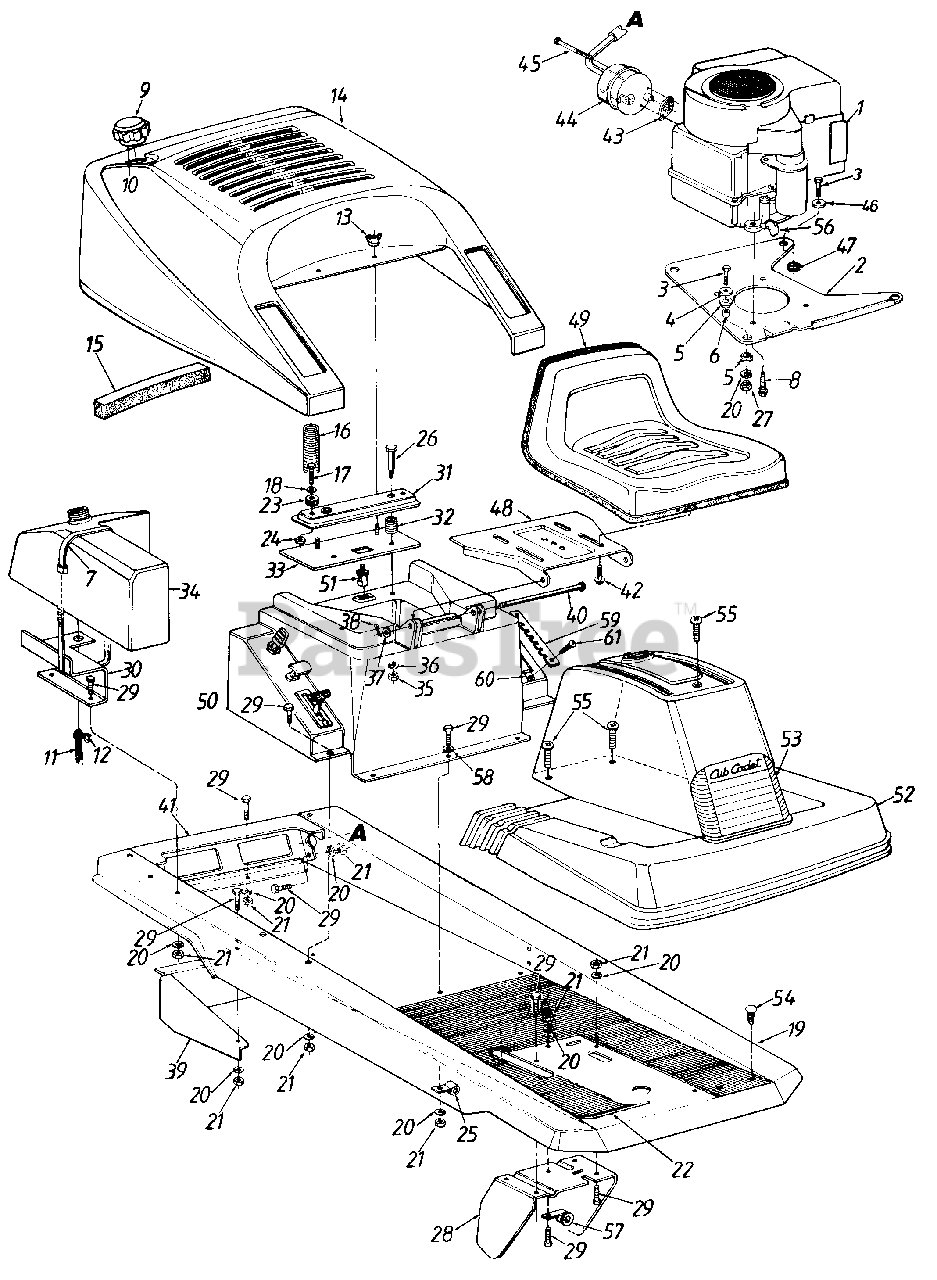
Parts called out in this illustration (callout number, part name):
1	Engine
4	Fl-Wash. .33" I.D. x 1.125" O.D
5	Engine Mounting Grommet
6	Spacer .315" I.D. x .5" O.D.
7	Cable Tie 30.6" Lg.
8	Hex Wash. Hd. Self-Tap Scr. 3/8-16 x 1.25" Lg.
10	Gas Cap Gasket
11	Gas Line
12	Hose Clamp
13	Wing Nut 1/4-20 Thd.
14	Rear Engine Cover
15	Foam Strip-2 Req'd.
16	Compression Spring 2.35" Lg.
17	Hex Bolt 5/16-18 x 718" Lg. (Gr. 5)
18	Fl-Wash. .344" I.D. x .875"
21	Hex Nut 5/16-18 Thd.
23	Elastemer Bushing
24	Hex Cent. L-Nut 5/16-18 Thd. (Gr. 5)
26	Shld. Bolt .5" Dia. x .84
27	Hex Nut 5/16-24 Thd.
28	Clutch Pedal Brkt. Ass'y.
29	Hex Bolt 5/16-18 x .75" Lg.
35	Hex Nut 3/8-16 Thd.
36	L-Wash. 3/8" I.D.
37	Fl-Wash. .469" I.D. x .88" O.D.
38	Cotter Pin 3/32" Dia. x 1.0" Lg.
43	Exhaust Gasket
45	Shld. Bolt 7/16" Dia. x 3-5/8"
46	Fl-Wash. .33" I.D. x 1.125" O.D.
47	Flange Washer .32" I.D. x .5"
48	Seat Pivot Bracket
49	Seat Ass'y.
50	Seat Support
51	Safety Switch (Seat)
52	Front Console
53	Headlight Lens
54	Ratchet Fastener .25" Dia. x .75" Lg.
55	Pan Hd. Tap Scr. #12 x .5" Lg.
56	90ø Elbow Male to Female
57	Cable Clip
58	Fl-Wash. .34" I.D. x .68" O.D.
59	Lift Reinforcement
60	Speed Nut #10-24 Thd.
61	Fl-Counter Sunk Scr. #10-24 x 1.5" Lg.
